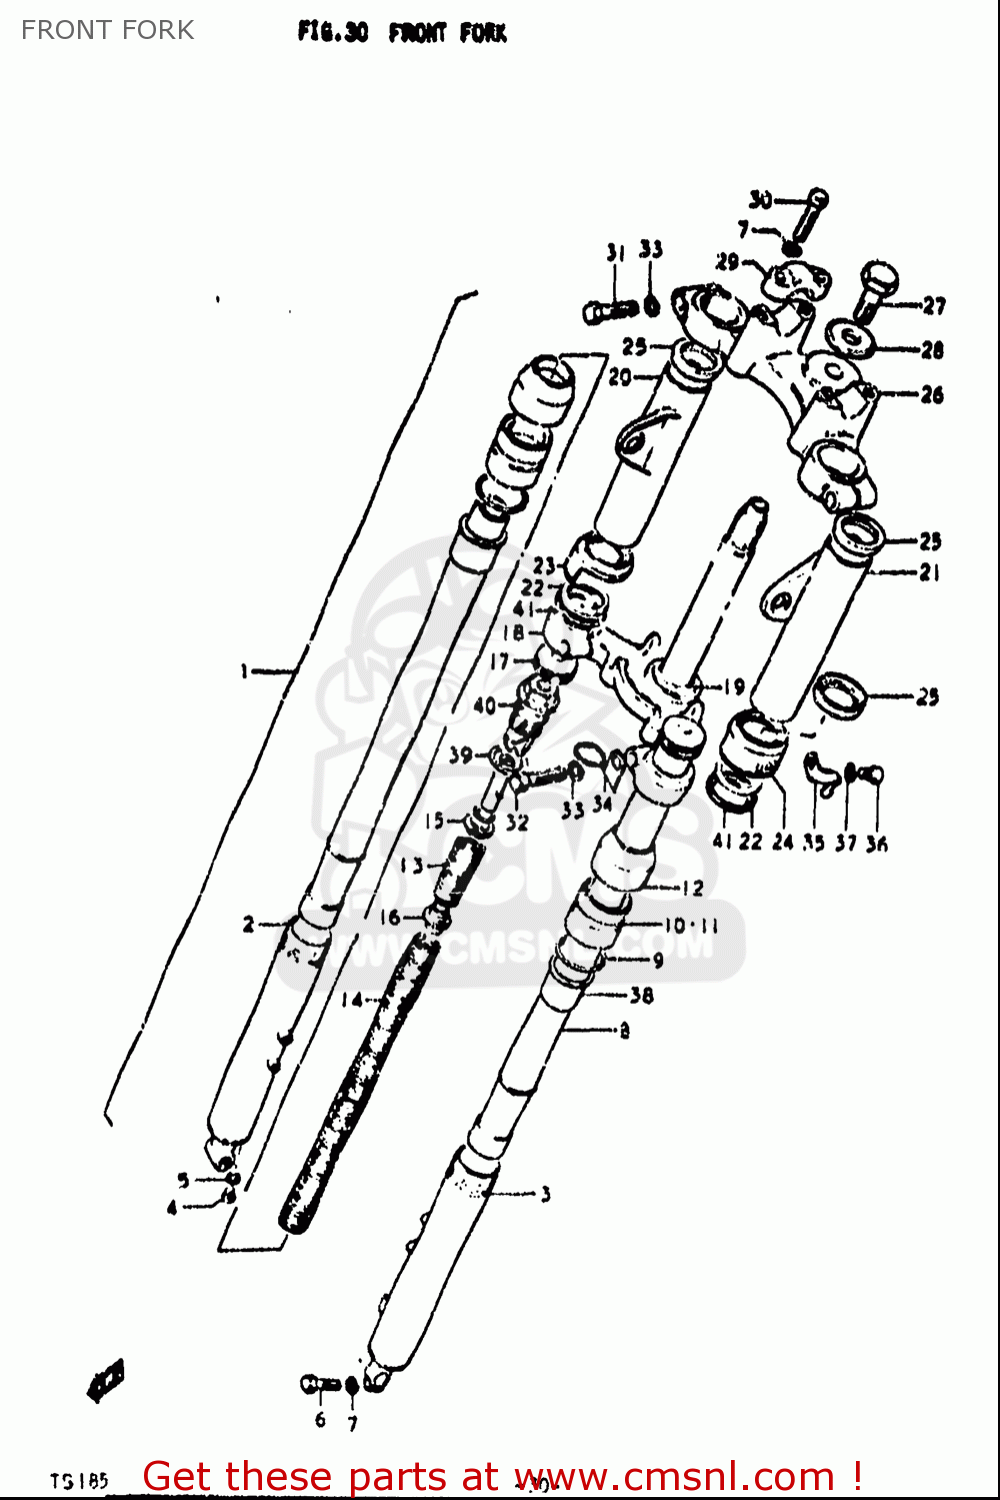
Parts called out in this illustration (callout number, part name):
4	SCREW
5	GASKET,DRAIN,PLUG (NAS)
6	BOLT
7	WASHER,LOCK
9	O RING,OIL SEAL LWR
11	SEAL,OIL
12	SEAL,DUST
15	GUIDE,SPRING
19	RACE,STEERING OUTER LWR
22	CUSHION,HEAD LAMP BRACKET
23	CUSHION,HEADLAMP BRACKET
25	SEAT,HEADLAMP BRACKET
26	HEAD,STEERING STEM
27	BOLT,FR FORK(10X33)
28	WASHER
29	HOLDER,HANDLEBAR
30	BOLT
31	BOLT,FORK INNER TUBE F
33	WASHER,LOCK
35	CLIP
36	SCREW
37	WASHER,LOCK
39	O RING
40	CAP
41	GUIDE, COVER
